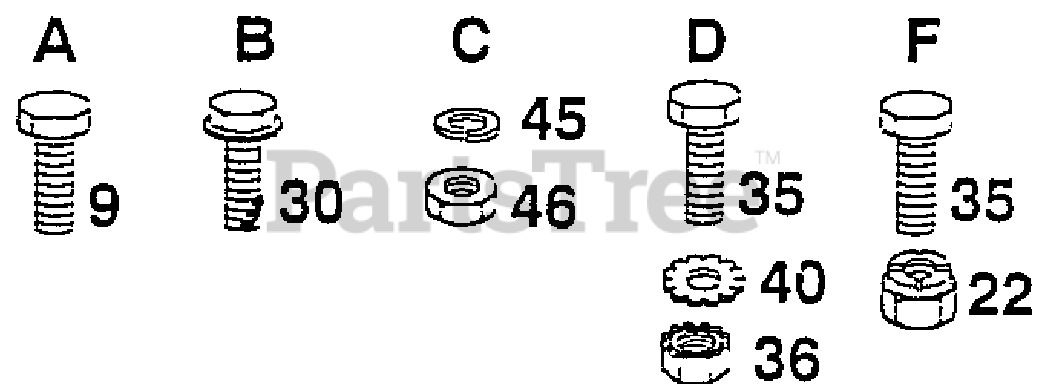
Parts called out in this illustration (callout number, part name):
9	Screw #10-24 x 1/2
22	Nut, Crownlock 1/4-20
30	Screw, Hex, Tap #10-24 UNC
35	Bolt, Hex 1/4-20 x 1/2 Grade 5
36	Nut, Hex, Keps 1/4-20
40	Washer, Lock, External Tooth 1/4
45	Washer, Lock 1/4
46	Nut, Hex, Jam 1/4-20
